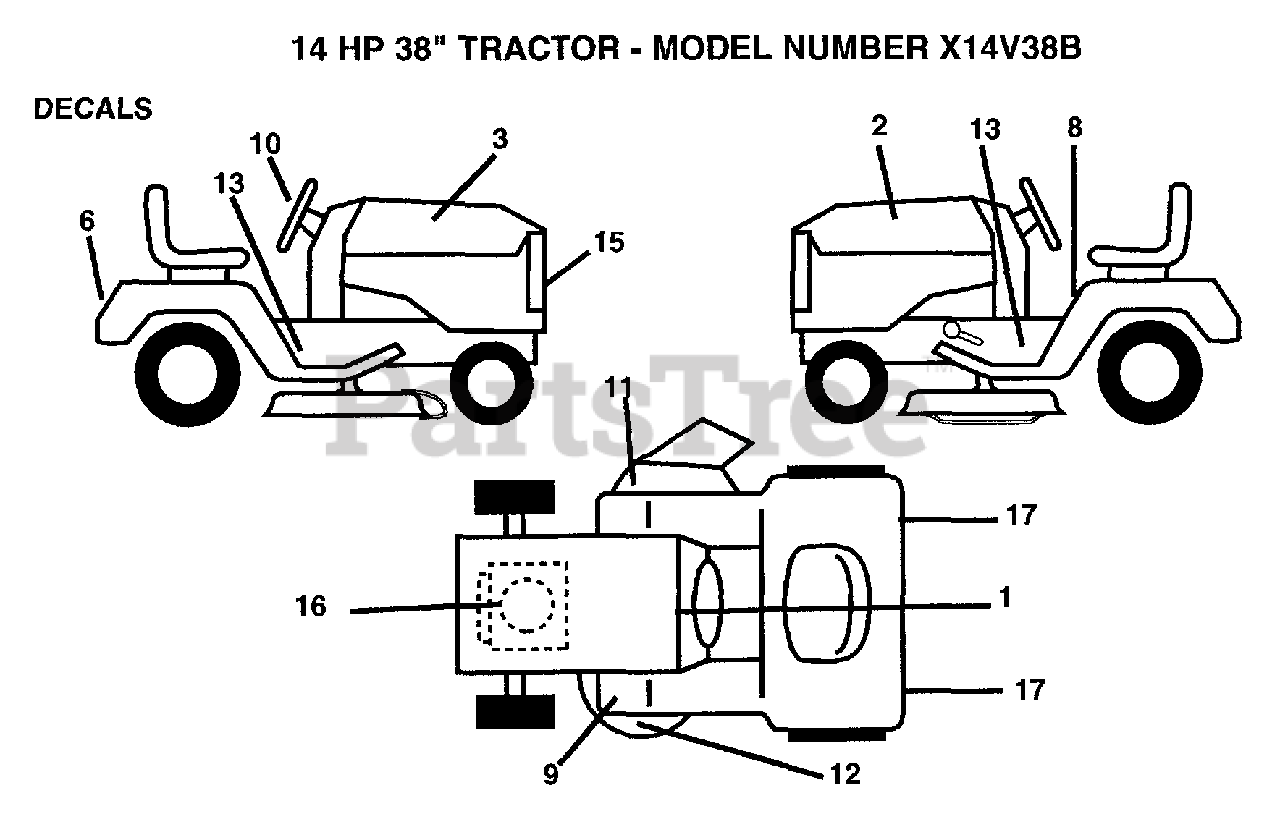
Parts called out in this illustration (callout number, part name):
3	HOOD DECAL RH
6	DECAL, FENDER
8	DECAL CAUTION
9	DECAL T
10	"DECAL,STR WHL "
11	DECAL WARNING
12	DECAL YT
13	DECAL, SPEED/DECK SIZE, CHASSIS
15	"DECAL,GRILL "
16	DECAL.ENG.805719
17	REFLECTOR, TAILLIGHT
